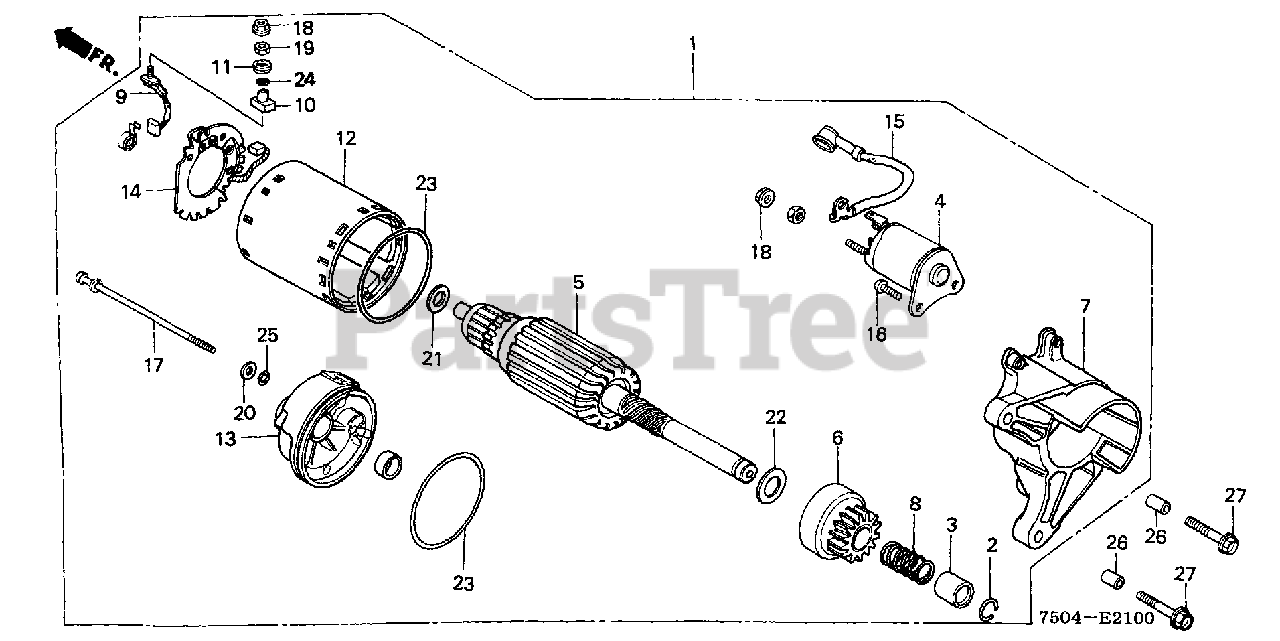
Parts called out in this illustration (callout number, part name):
1	MOTOR ASSY., STARTER
2	RING, SNAP
3	COLLAR, CLUTCH
4	CONTACTOR ASSY.
6	CLUTCH, OVERRUNNING
7	HOUSING, DRIVE SIDE
9	BRUSH
10	BUSHING, INSULATION
11	BUSHING, INSULATION
12	YOKE
13	FRAME, STARTER END
14	PLATE, BRUSH HOLDER
15	WIRE, WATER COVER (NOT AVAILABLE)
15	WIRE, WATER COVER
16	BOLT
17	BOLT, THROUGH (NOT AVAILABLE)
20	WASHER, STEEL PLATE
21	WASHER
24	O-RING
26	PIN A, DOWEL (10X16)
27	BOLT, FLANGE (8X35)
